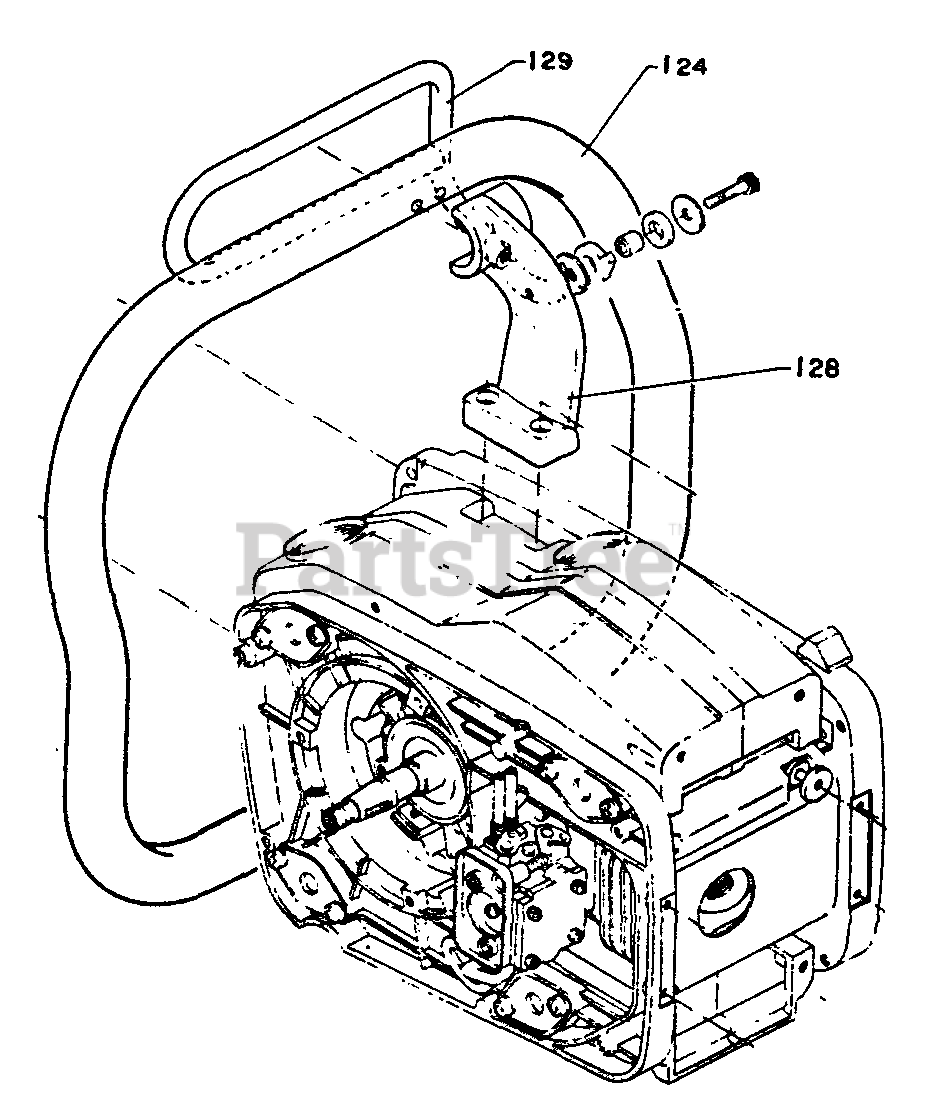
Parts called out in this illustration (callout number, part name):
124	LOOP HANDLE
128	LOOP HANDLE SUPPORT
129	HAND GUARD (LOOP HANDLE)
